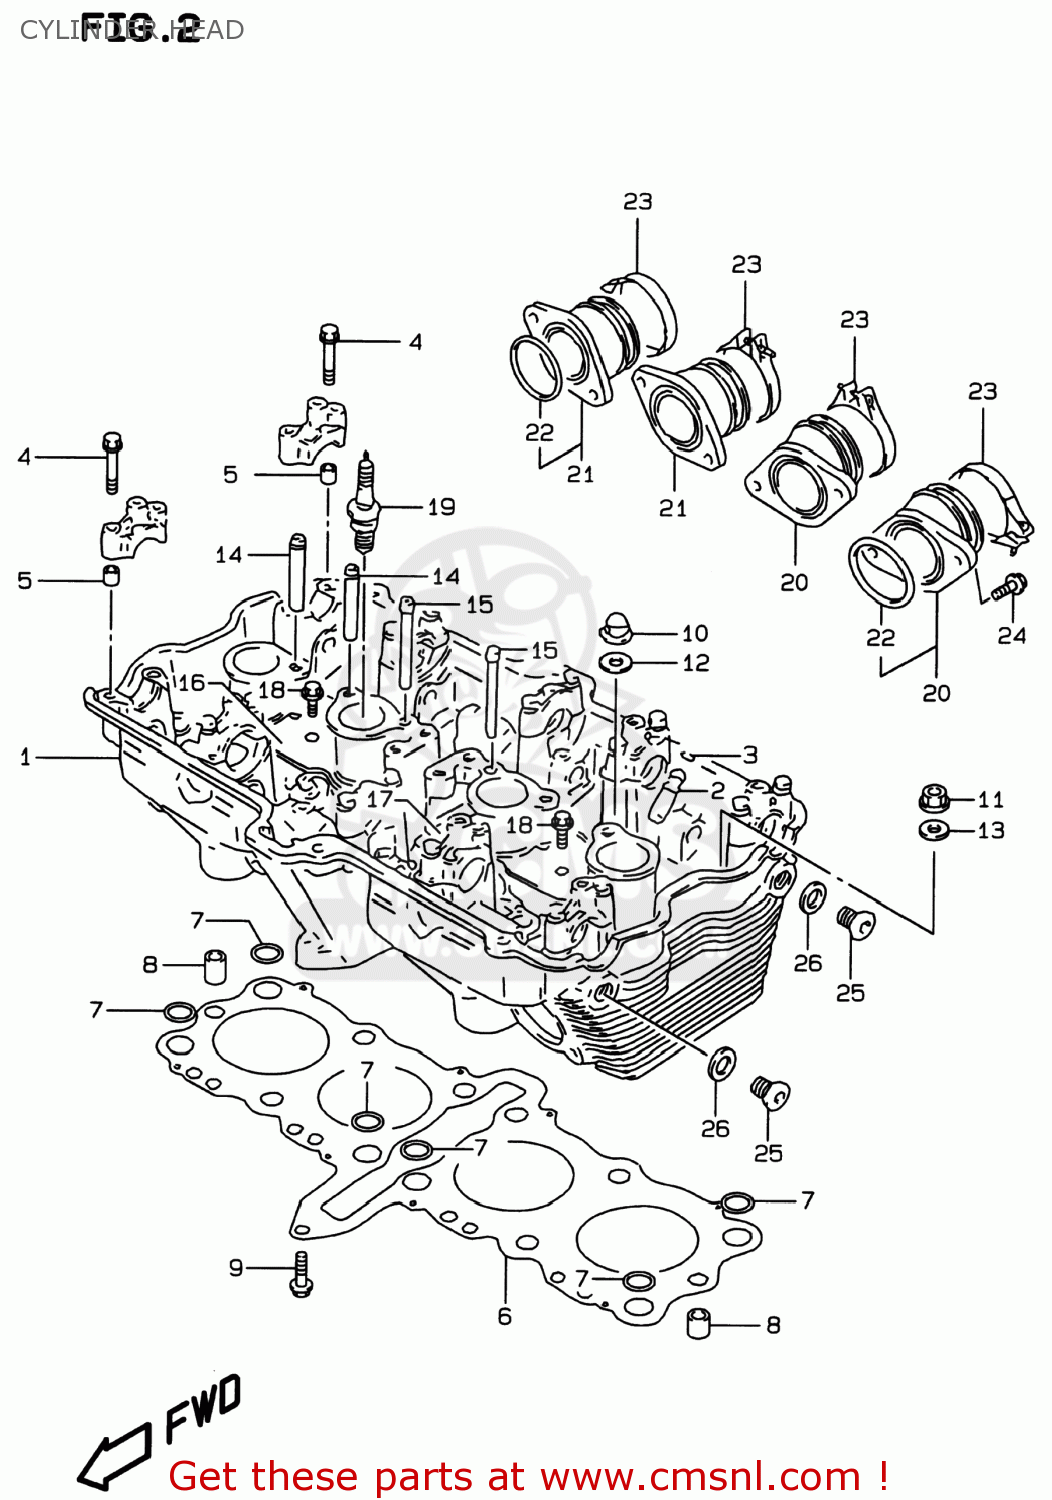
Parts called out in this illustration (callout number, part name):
1	HEAD ASSY,CYLINDER
2	GUIDE,VALVE
3	RING,SNAP
4	BOLT(6X39)
5	PIN(6.2X8X11)
6	GASKET,CYLINDER HEAD (NAS)
7	O RING(D:2.6,ID:12.1)
8	PIN
9	BOLT
10	NUT
11	NUT
12	GASKET(10.2X20X2).3 (NAS)
13	WASHER (10.5X22X2.3)
14	PIPE,OIL NO.1
15	PIPE,OIL NO.3
16	PLATE,OIL PIPE,R
17	PLATE,OIL PIPE,L
18	BOLT
19	PLUG,SPARK(CR9EK)
20	PIPE ASSY,INTAKE,L
21	PIPE ASSY,INTAKE,R
22	O RING(D:2.4,ID:39.7)
23	CLAMP
24	BOLT MAGNETO S
25	PLUG
26	GASKET(13.8X18.8X4.8) (NAS)
